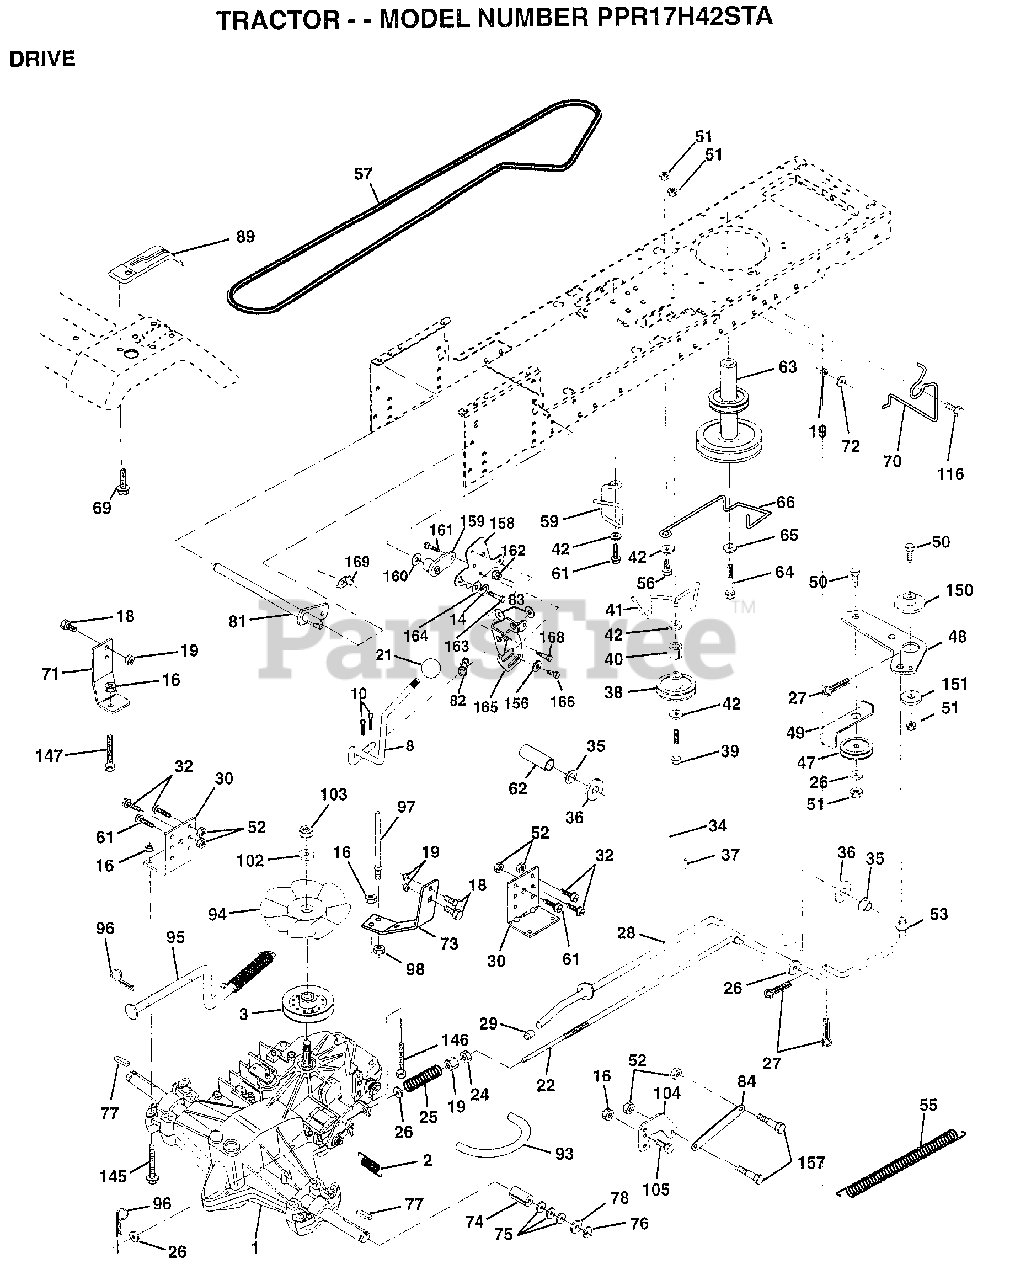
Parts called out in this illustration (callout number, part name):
2	SPRING RET BRAKE
3	PULLEY.TRANSAXLE
8	ROD.SHIFT.FENDER.ADJ.LT.CRD
10	PIN COTTER 1/8
14	LOCKWASHER
16	NUT
18	BOLT
19	NUT
21	KNOB DLX BLK/BLK
22	ROD.BRAKE.HYDRO.
24	NUT
25	SPRING ROD LT
26	WASHER
27	COTTER PIN
28	ROD.BRAKE.PARK.LT
29	PLUNGER CAP T
30	TRANSAXLE MTG BKT
32	BOLT
34	SHAFT ASM-PEDAL F
35	NYLON BEARING
36	WASHER LT
38	FLAT IDLER PULLEY
39	BOLT
40	SPACER T
41	"KEEPER,BELT.IDLER FLAT"
42	WASHER
48	BELLCRANK.CLUTCH
49	RETAIN BELT
53	"LINK, CLUTCH T"
55	"SPRING, RETURN LT"
57	"BELT.GD DRV 82"""
59	KEEPER BELT CNTSP
61	SCREW
62	PEDAL COVER T
63	PULLEY.ENGINE
64	BOLT
65	LOCKWASHER
66	KEEPER-BELT
69	SCREW HEXWSH H-L
70	KEEPER BELT ENG
71	STRAP TORQ LH HYD
72	WASHER
73	"STRAP-TORQUE,RH"
74	SPACER SPLIT
75	WASHER
76	E-RING LT
77	SQUARE KEY
78	WASHER
81	SHAFT.ASM.CROSS
82	"SPRING,TORSION"
83	WASHER
84	LINK.TRANSAXLE.LT/YT
89	CONSOLE.SHIFT.LT
93	"LINE FUEL HYD 4"""
94	"FAN 7"" HYDRO"
96	RETAINER M
97	BOLT KEEPER RH
98	NUT
102	WASHER BELLEVILLE
104	ARM CONTROL HYDRO
105	SCREW CAP 5/16-18
116	BOLT RDHD 3/8-16
145	BOLT.HEX.FLGHD
146	BOLT.HEX.FLGHD.
147	BOLT.HEX.FLGHD
150	BUSHING.BELLCRANK.GRD.DR
151	WASHER
156	WASHER.SRRTD.5/16
157	"BOLT,SHOULDER"
158	BRKT.SHIFT.MOUNT
159	HUB.SHIFT
160	WASHER
161	BOLT T
164	WASHER.5/8X.281X10GA
165	BRKT.PIVOT.LEVER
166	SCREW.5/16-18X5/8
168	BOLT.SHOULDER.5/16-18X.561
169	PLATE.FASTENING
